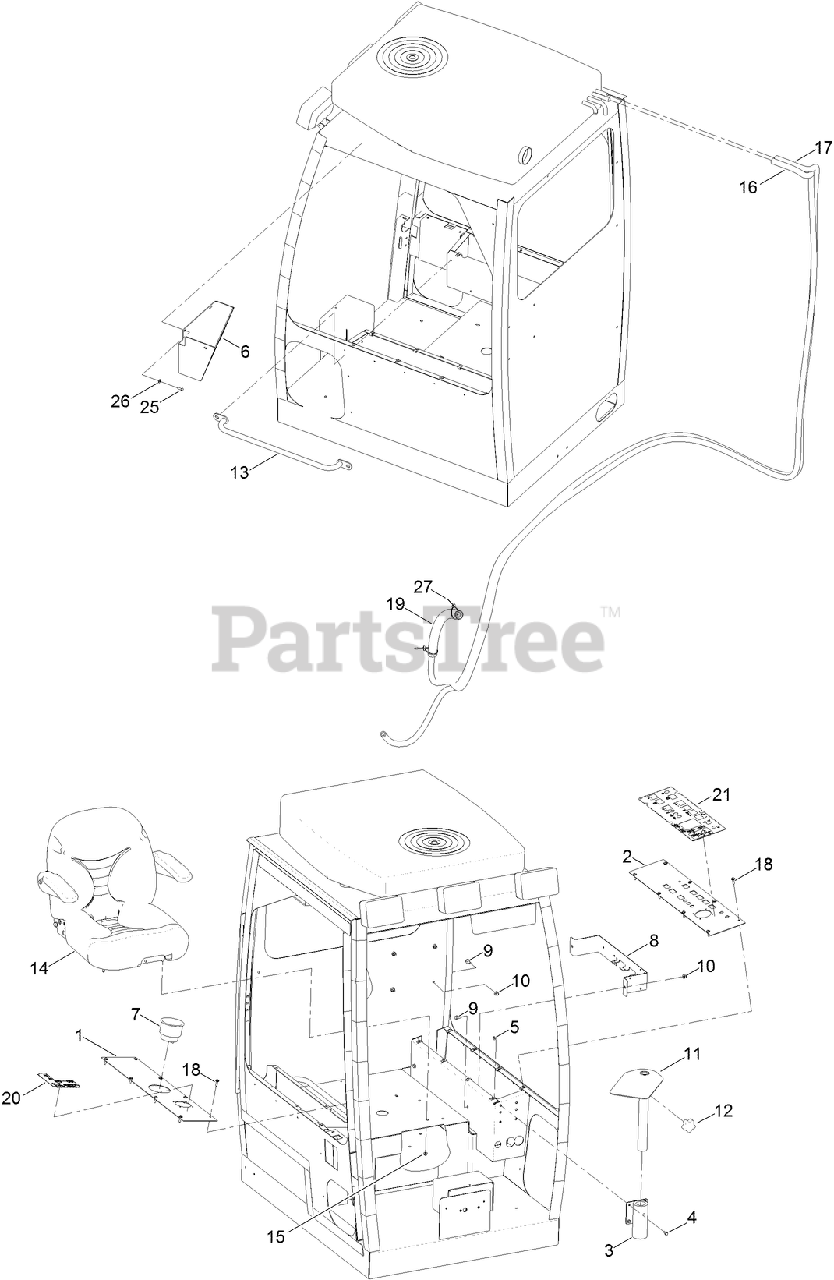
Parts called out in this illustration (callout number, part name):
1	PLATE-CONSOLE, RH
2	PLATE-CONSOLE, LH
3	MOUNT-DISPLAY
4	SCREW-HHF
5	NUT-FLANGE, NI
6	HOUSING-DISPLAY
7	CUP-HOLDER
8	PLATE-MOUNTING, ELECTRICAL
9	SCREW-HHF
10	NUT-LOCK, HHF
11	MOUNT-LOCATOR
12	KNOB-ADJUSTMENT
13	HANDLE-CAB
14	OPERATOR SEAT ASM (STATIC)
15	NUT-HF, NI
16	HOSE-HEATER
17	HOSE-HEATER
18	SCREW-PPH
19	SLEEVE-THERMAL
20	DECAL-JOYSTICK, RIGHT
21	DECAL-JOYSTICK, LEFT
25	SCREW-HH
26	WASHER-FLAT
27	TIE-CABLE
